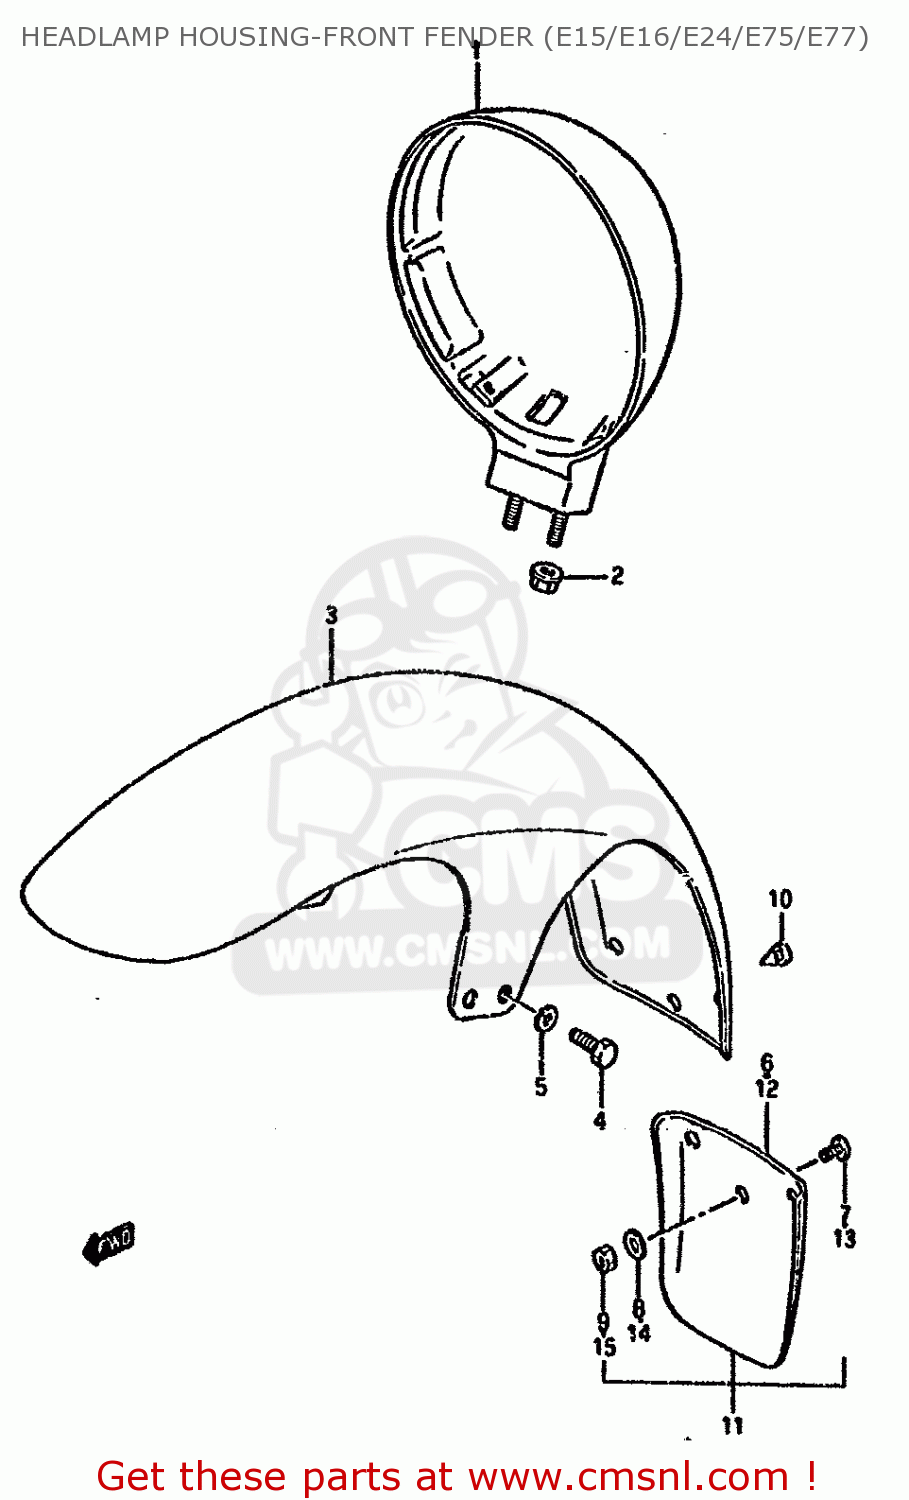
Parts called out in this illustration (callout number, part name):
1	HOUSING,HEADLAMP
2	NUT
3	FENDER,FRONT (BLUE)
4	BOLT
5	WASHER,LOCK
6	EXTENSION
7	SCREW 5X10
8	WASHER,5MM
9	NUT 5MM
10	PLUG(OD:10)
11	EXTENSION,FRONT FENDER
12	EXTENSION
13	SCREW 5X10
14	WASHER,5MM
15	NUT 5MM
